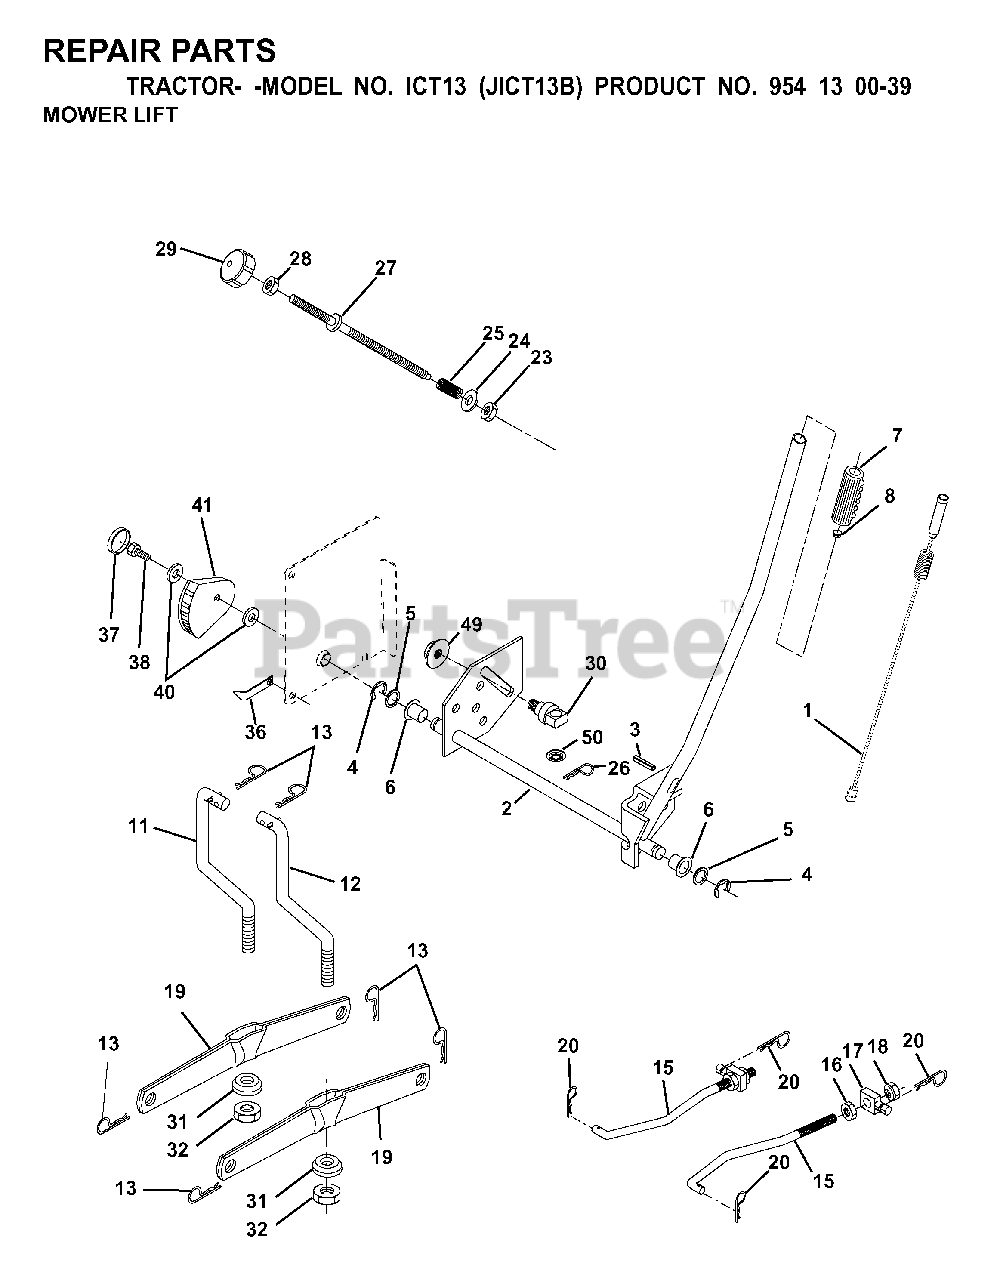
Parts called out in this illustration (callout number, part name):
1	WIRE ASM INNER W/ PLUNGER LT
2	SHAFT ASM R HANDLE
3	PIN GROOVE
4	RETAINING RING LT
6	BEARING.NYLON
7	GRIP HANDLE
8	PLUNGER BUT KIT
11	LINK
12	LINK
13	RETAINER-SPRNG RB
15	LINK FRONT
16	NUT
17	TRUNION
18	NUT
19	ARM.REAR.SUSPENSION
20	SPRING RETAINER
25	SPRING**
26	RETAINER CLIP
27	ROD ADJ LIFT
28	NUT
29	KNOB INF 3/8-16
31	BEARING PIVOT
32	NUT CROWNLOCK 3/8-24
36	POINTER, HEIGHT INDICATOR
37	PLUG,HOLE
38	SCREW 5/16-18X1
41	HEIGHT INDICATOR
49	NUT
50	NUT PUSH M
